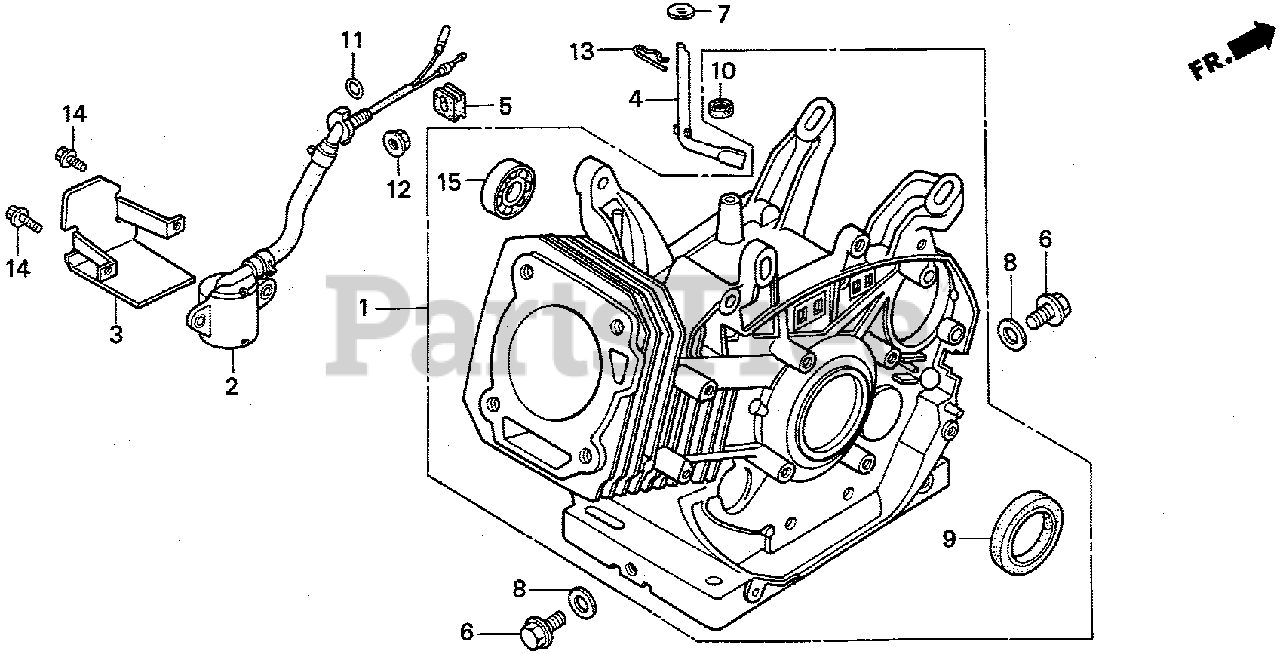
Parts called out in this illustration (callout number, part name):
1	CYLINDER ASSY. (SELFSTARTER+ALERT)
2	SWITCH ASSY., OIL LEVEL
3	PLATE, OIL LEVEL SWITCH
4	SHAFT, GOVERNOR ARM
5	GROMMET, WIRE
6	BOLT, DRAIN PLUG
7	WASHER (8.2X17X0.8)
8	WASHER, DRAIN PLUG (12MM)
9	OIL SEAL (35X52X8)
10	OIL SEAL (8X14X5)
11	O-RING (13.5X1.5) (ARAI)
12	NUT, FLANGE (10MM)
13	PIN, LOCK (8MM)
14	BOLT, FLANGE (6X12)
15	BEARING, RADIAL BALL (6202)
